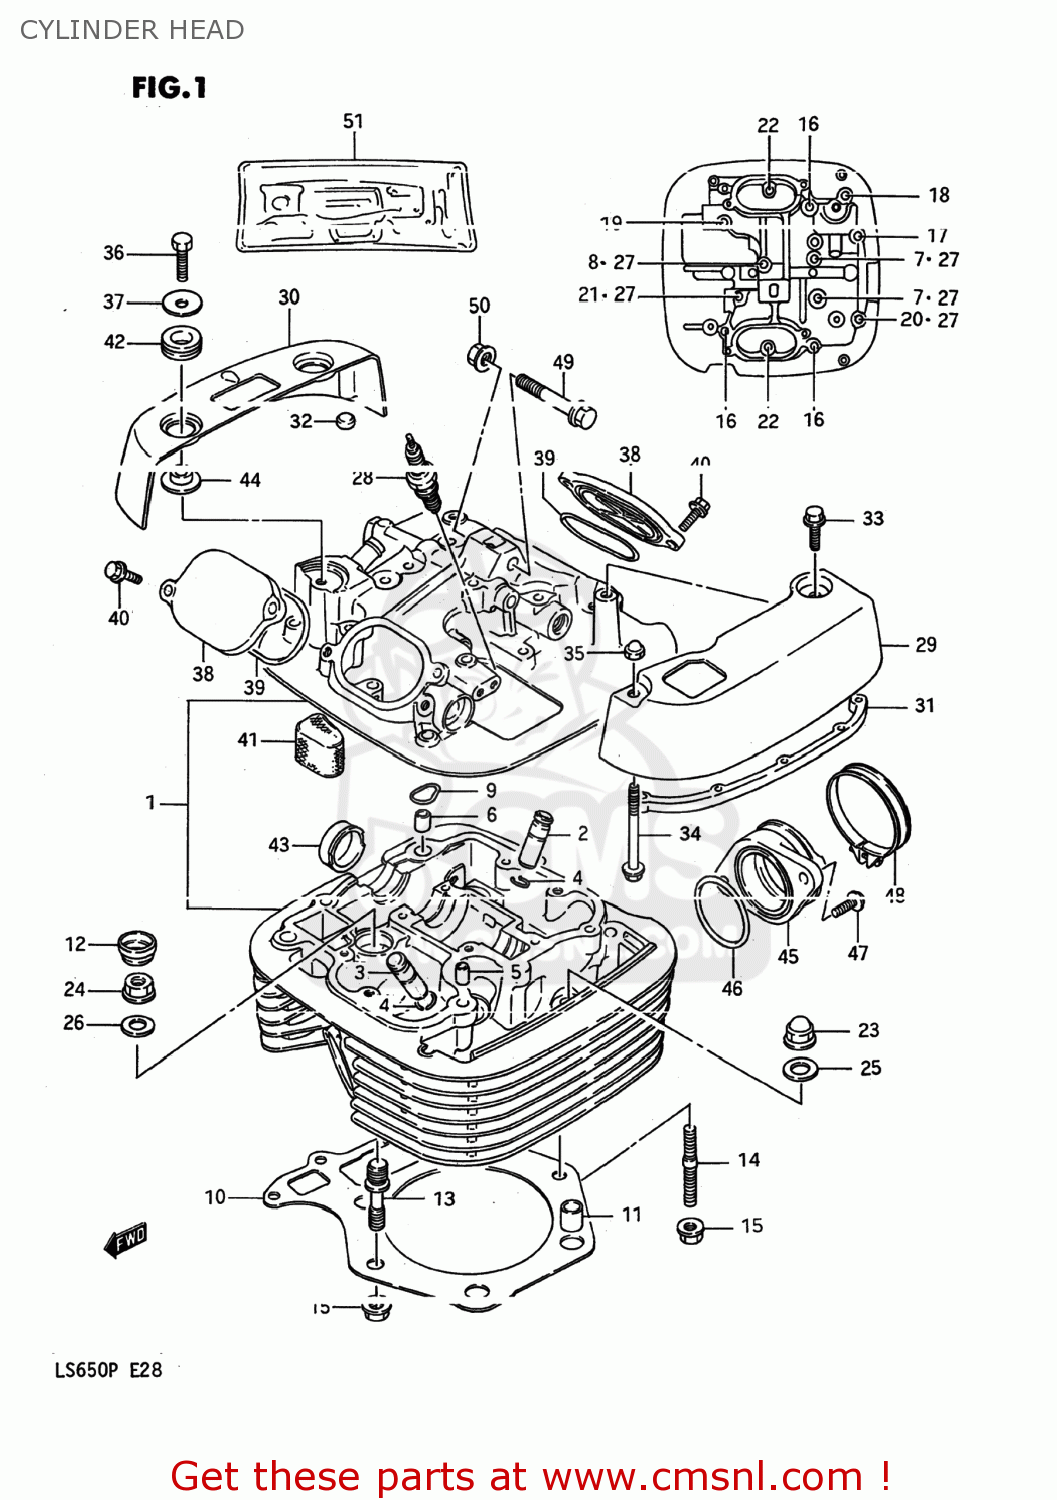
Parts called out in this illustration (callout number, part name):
1	HEAD ASSY,CYLINDER
2	GUIDE,VALVE
3	GUIDE,VALVE
4	RING,SNAP
5	PIN(6.2X8X11)
6	PIN(11X14)
7	BOLT(6X60)
8	BOLT(6X70)
9	O RING,CYL HEAD COVER
10	GASKET,CYLINDER HEAD (NAS)
11	PIN
12	NUT,CYLINDER HEAD SEAL
13	BOLT,STUD
14	BOLT,STUD(8X31)
15	NUT
16	BOLT(6X39)
17	BOLT(6X125)
18	BOLT(6X115)
19	BOLT(6X60)
20	BOLT(6X130)
21	BOLT(6X55)
22	BOLT 6X25
23	NUT
24	NUT
25	GASKET(10.5X22X2) (NAS)
26	GASKET(10.2X20X2).3 (NAS)
27	GASKET(5.8X13X1.2) (NAS)
28	PLUG,SPARK(DPR8EA-9)
29	CAP,HEAD COVER,L
30	CAP,CYLINDER HEAD COVER,R
31	CUSHION,HEAD COVER CAP,L
32	CUSHION,R CAP
33	BOLT 6X20
34	BOLT 6X65
35	NUT
36	BOLT
37	WASHER (6.5X24X1.6)
38	CAP,INSPECTION
39	O RING(D:2.4,ID:23)
40	BOLT 6X20
41	SEPARATOR,OIL BREATHER COVER
42	CUSHION
43	PLUG(OD:30)
44	BUSH
45	PIPE,INTAKE
46	O RING(D:2.4,ID:45.7)
47	SCREW
48	CLAMP
49	BOLT
50	NUT
51	GASKET SET (NAS)
